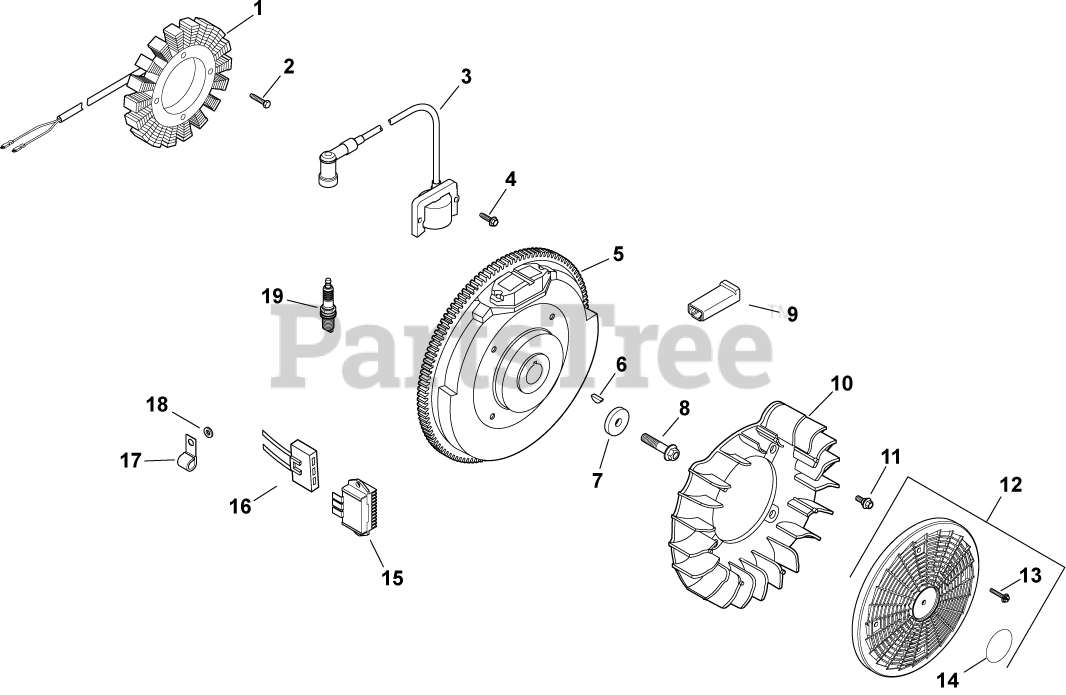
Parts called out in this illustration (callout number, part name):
1	KIT, 15 / 20 AMP STATOR
2	SCREW, M5X0.8X25 - (#25086402S)
3	MODULE, IGNITION
4	SCREW, FLG THD FRM M5X.8X20-(#25086399S)
5	FLYWHEEL ASSEMBLY (LW)
6	KEY, 3/16" X 5/8"
7	WASHER, FLAT 13/32"
8	SCREW, FLG M10X1.5X45 - (#25086361S)
9	CONNECTOR (1 CONTACT)
10	FAN USE 24 755 253-S
11	BOLT, SHOULDER
12	KIT, GRASS SCREEN
13	SCREW, FLG SEMS M4X.7X25
14	DECAL, GRASS SCREEN USE 24 113 499-S
15	REG/RECTIFIER (20/25 AMP)-USE 25 403 20-
16	CONNECTOR
17	CLIP, CABLE
18	WASHER, FLAT 1/4" (O.D. 1/2")
19	PLUG, SPARK (PRO SERIES)
2458452-S	MODULE, SPARK ADV -USE 24 584 89-S
